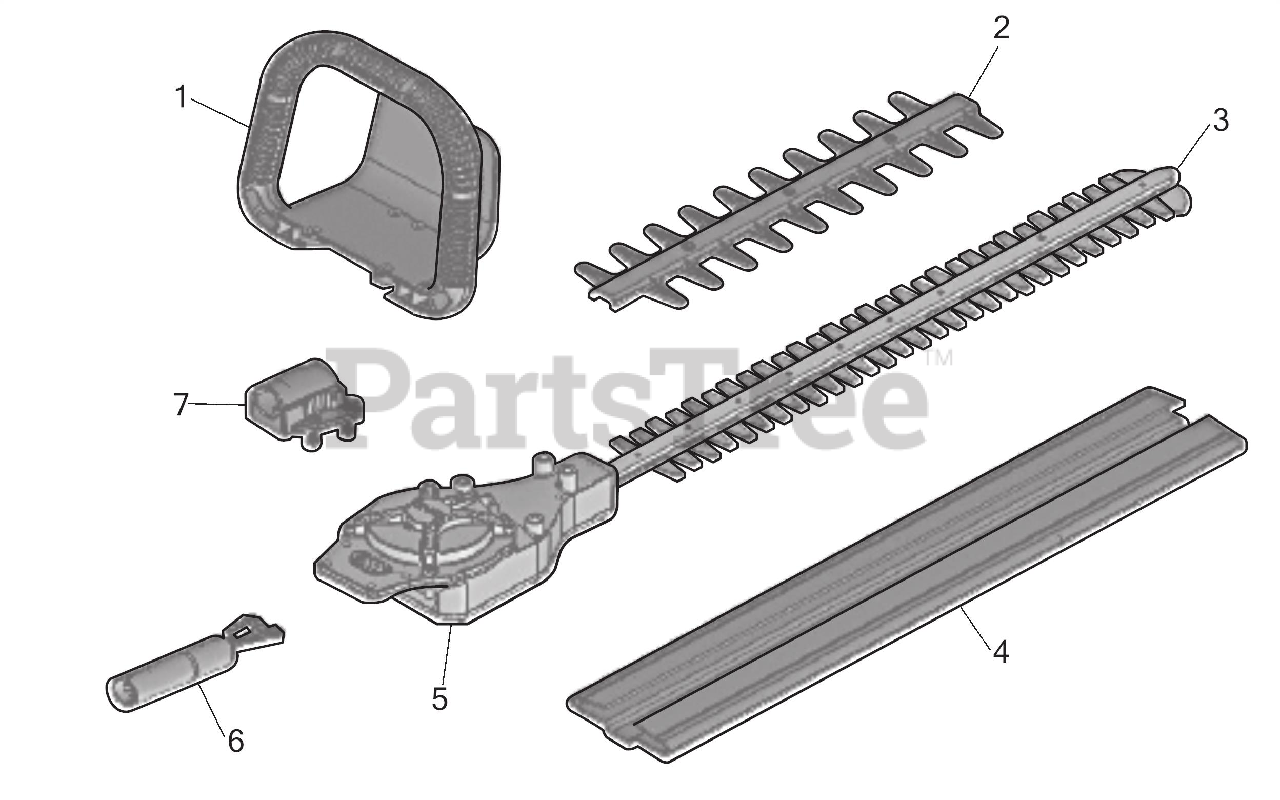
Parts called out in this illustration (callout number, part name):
1	HANDLE ASSEMBLY CPL410 CORE
2	BLUNT W/HDW CPL410 CORE
3	BLADE ASSEMBLY HT CPL410 CORE
4	BLADE COVER
5	GEARBOX ASSEMBLY W/MTR CPL410 CORE
6	BOOM ASSEMBLY CPL410 CORE
7	CLAMP ASSEMBLY W/HDW CPL410 CORE
